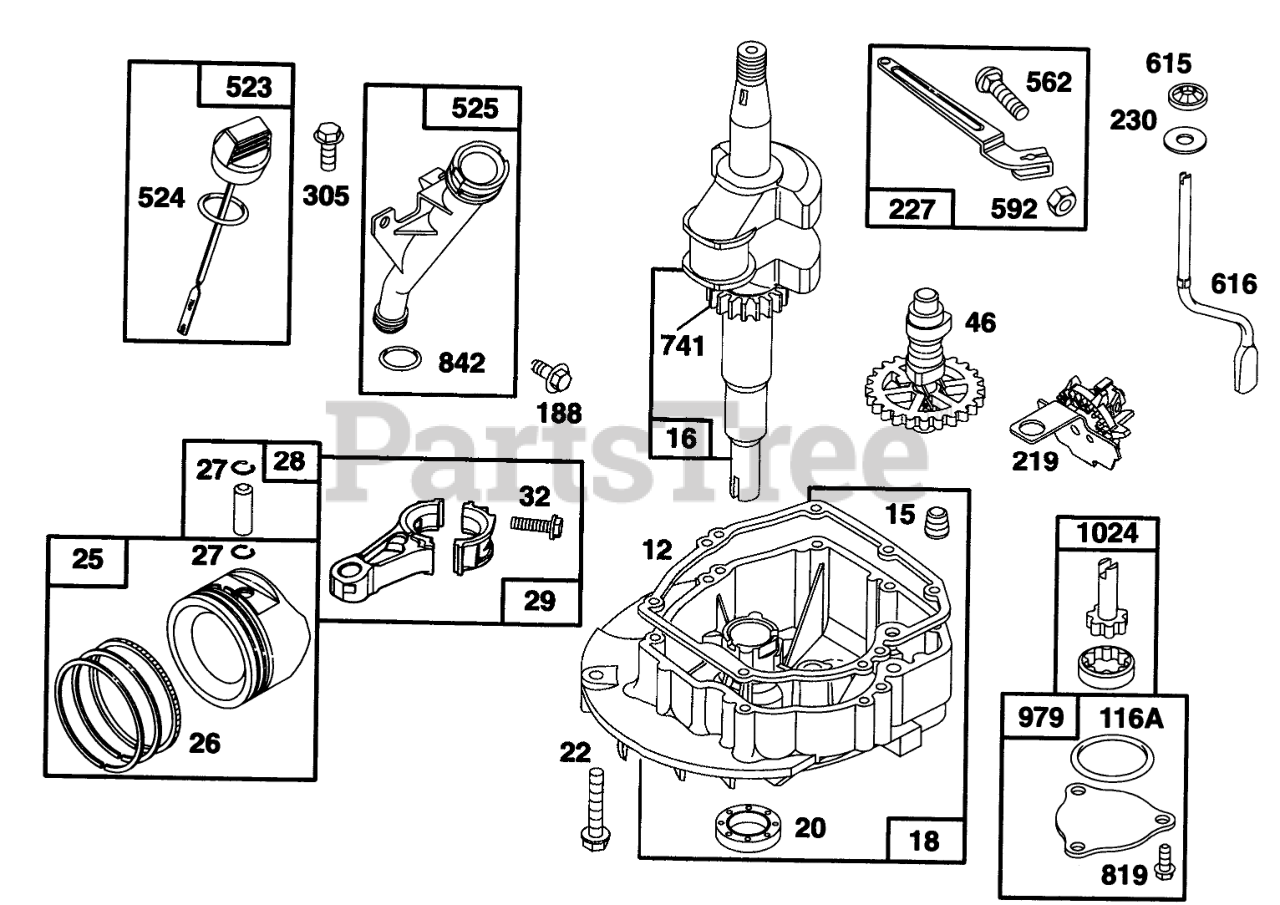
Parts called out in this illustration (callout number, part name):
12	ENGINE BASE GASKET
15	PIPE PLUG
16	CRANKSHAFT
18	ENGINE SUMP
20	SEAL-OIL
22	SCREW - ENGINE BASE
25	STD PISTON ASSEMBLY
26	STD RING SET
27	PISTON PIN LOCK
28	PIN ASM - PISTON
29	CONNECTING ROD
32	Connecting Rod
46	CAM GEAR
116A	O RING SEAL
188	Screw-Cap
219	GOVERNOR/OIL SLINGER
227	GOVERNOR LEVER ASSEMBLY
230	WASHER
305	SCREW - HEX HEAD
523	DIPSTICK-OIL
524	O-RING
525	OIL FILLER TUBE
562	GOVERNOR LEVER BOLT
592	HEX NUT
615	FASTENER
616	GOVERNOR CRANK
741	TIMING GEAR
819	SCREW - SEM
842	O-RING
979	OIL PUMP COVER
1024	OIL PUMP
